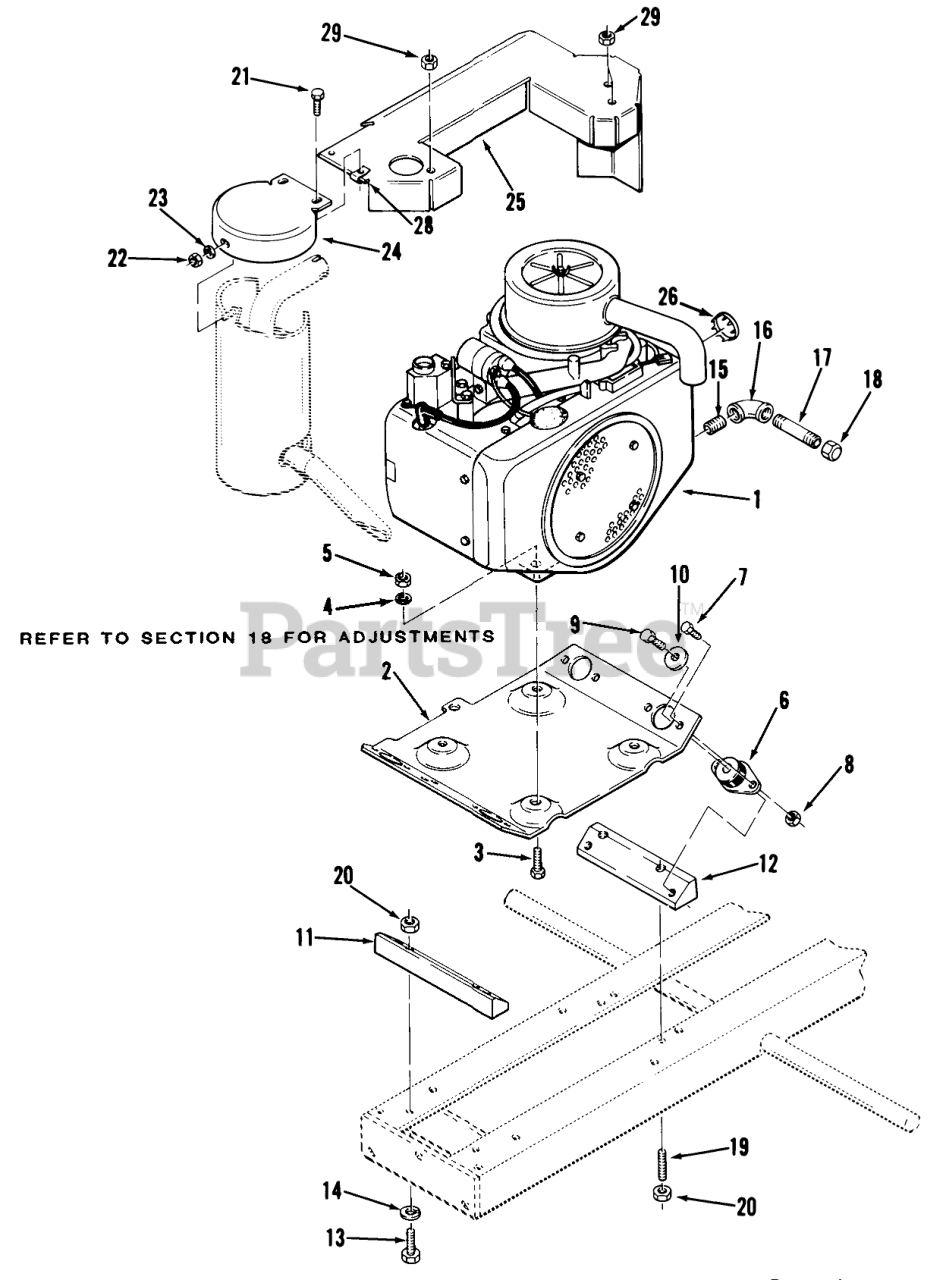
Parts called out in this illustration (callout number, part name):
1	Engine 17 HP Kohler KT-17S Spec 24223
2	PLATE
3	Bolt
4	Washer
5	Nut
6	MOUNT-ISOLATION
7	H H C S
8	Nut
9	Bolt
10	Washer
11	Engine Mounting Block-Front
12	MOUNT BLOCK-REAR
13	BOLT
14	LOCKWASHER
15	Nipple 3/8
16	Elbow 3/8
17	Nipple 3/8 x 4 1/2
18	Cap
19	SET SRW 3/8X16-1 3/4
20	Nut
21	Screw
22	Nut
24	CAP-MUFFLER SHIELD
25	ASSY HEAT SHIELD
26	Plug Button
29	Flanged Nut
